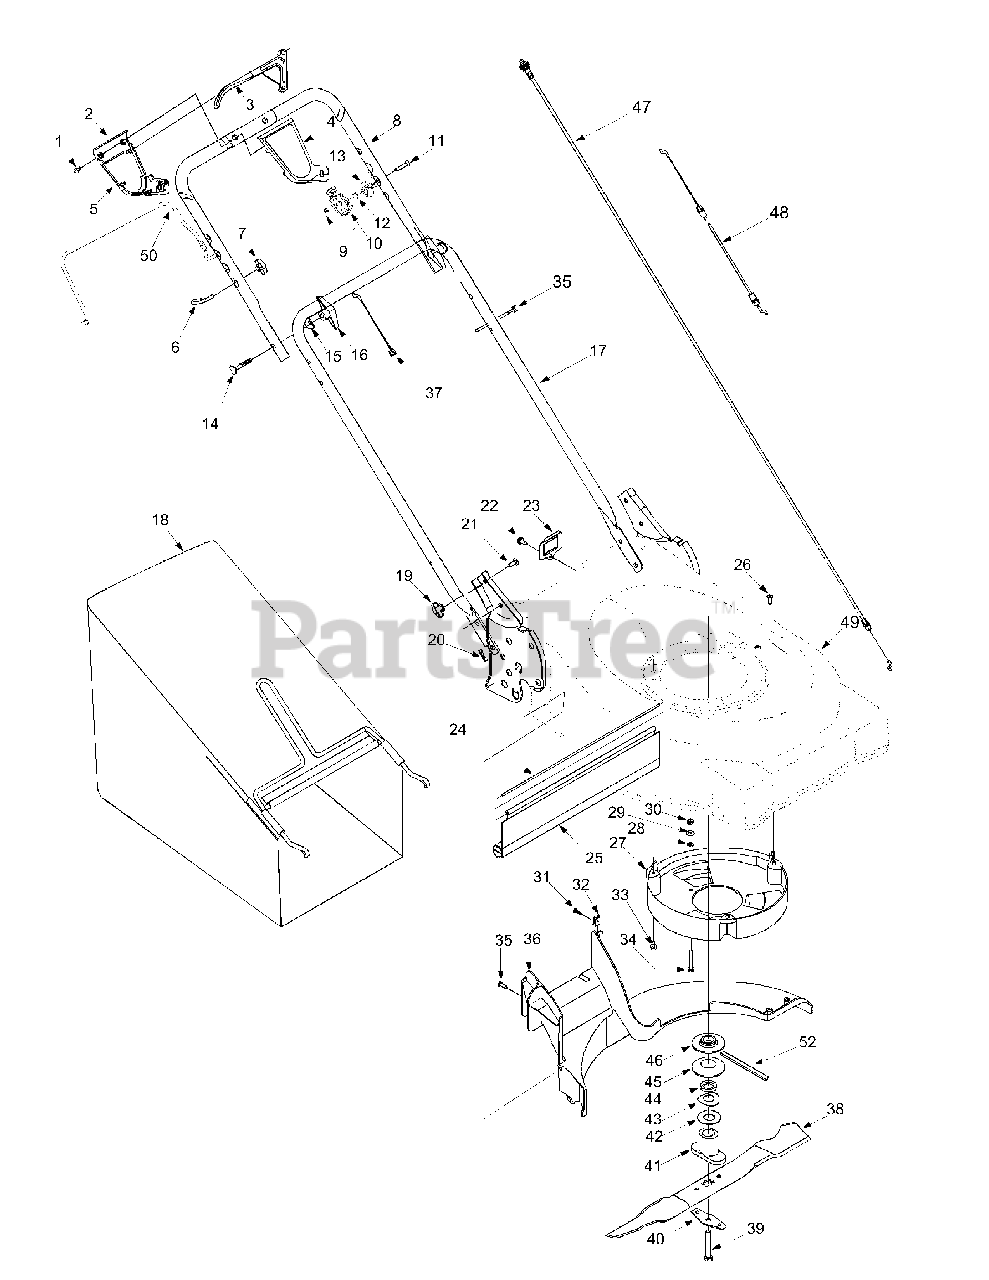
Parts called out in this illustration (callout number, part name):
1	Hi-Lo Screw
2	Control Housing: Lower
3	Drive Control Lever
4	Control Housing: Upper
5	Mounting Cap: SP Cable
6	Eye Bolt
7	Handle Knob
8	Upper Handle
9	Hex Lock Nut 1/4-20
10	Throttle Housing
11	Machine Screw 1/4-20 x 1.825"
12	Spring Washer
13	Throttle Lever
14	Carriage Bolt 5/16-18 x 2.0"
15	Saddle Washer
16	Knob Assembly
18	Grasscatcher Assembly
19	Wing Nut
20	Hairpin Clip
21	Hex Bolt
22	TT Screw 1/4-20 x 0.625"
23	Pulley Cover
24	Trailshield Wire
25	Trailshield
26	Hi-Lo Screw #12-14 x 0.750"
27	Belt Cover
28	Flat Washer
29	Lock Washer
30	Hex Nut 1/4-20
31	B Screw #10-16 x 0.5"
32	U Nut
33	TT Screw 1/4-20 x 0.375"
34	TT Screw 1/4-20 x 1.75"
35	Cable Tie
36	Rear Baffle
37	S.P. Cable
38	Mulching Blade
39	Hex Bolt 3/8-24 x 2.5"
40	Blade Bell Support
41	Blade Adapter
42	Flat Washer
43	Spring Washer
44	Engine Spacer
45	Pulley Half
46	Pulley Half: Upper
47	Choke Cable
48	Control Cable
49	Cutting Deck Assembly
50	Blade Control Bail
51	Front Baffle
52	Belt 3/8 x 39"
